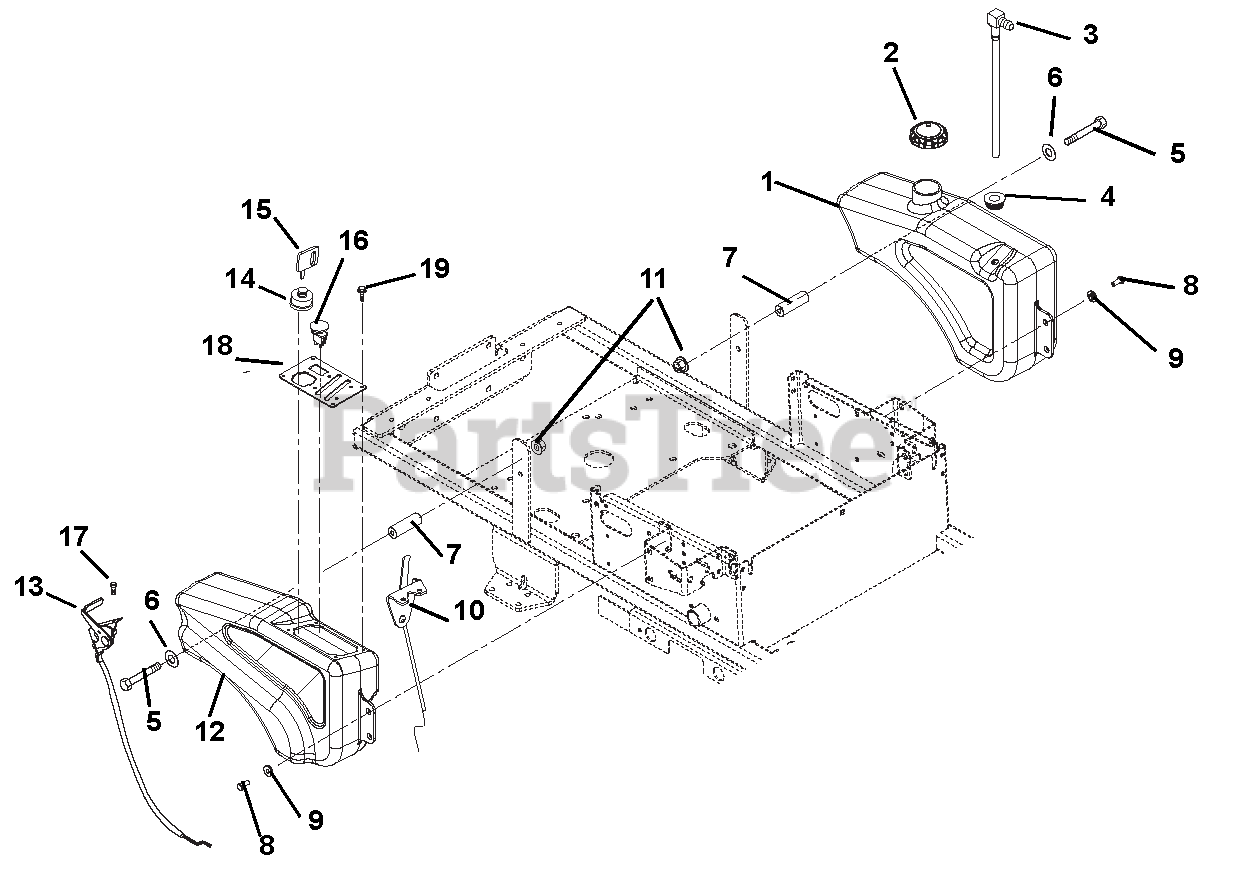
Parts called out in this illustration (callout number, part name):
1	GAS TANK, ZOOM
2	FUEL CAP
3	FITTING, TANK
4	BSHG-FLG .375 X 1.062 X .625 R
5	@BLT-HEX .31-18X3.50 GR5 YWZC
6	@WSHR-FL-STL.38X.875X.083 YWZC
7	SPCR, FLG .32X.49X.15X2.64
8	@BLT-HEX .31-18X.75 GR5 YWZC
9	BSHG, FLG .325X.499X.26X.88
10	CABLE, CHOKE
11	@NUT-LK-NYL-FLG .31-18 YWZC
12	FENDER, ZOOM
13	CABLE, THROTTLE
14	KEY SWITCH
15	KEY -W/CAP
16	SWITCH, CLUTCH
17	@SCR-TAP 10-24X.50 HWH TR YWZC
18	PANEL, ZOOM CONTROL
19	RIVET, PLASTIC .195 DIA.
